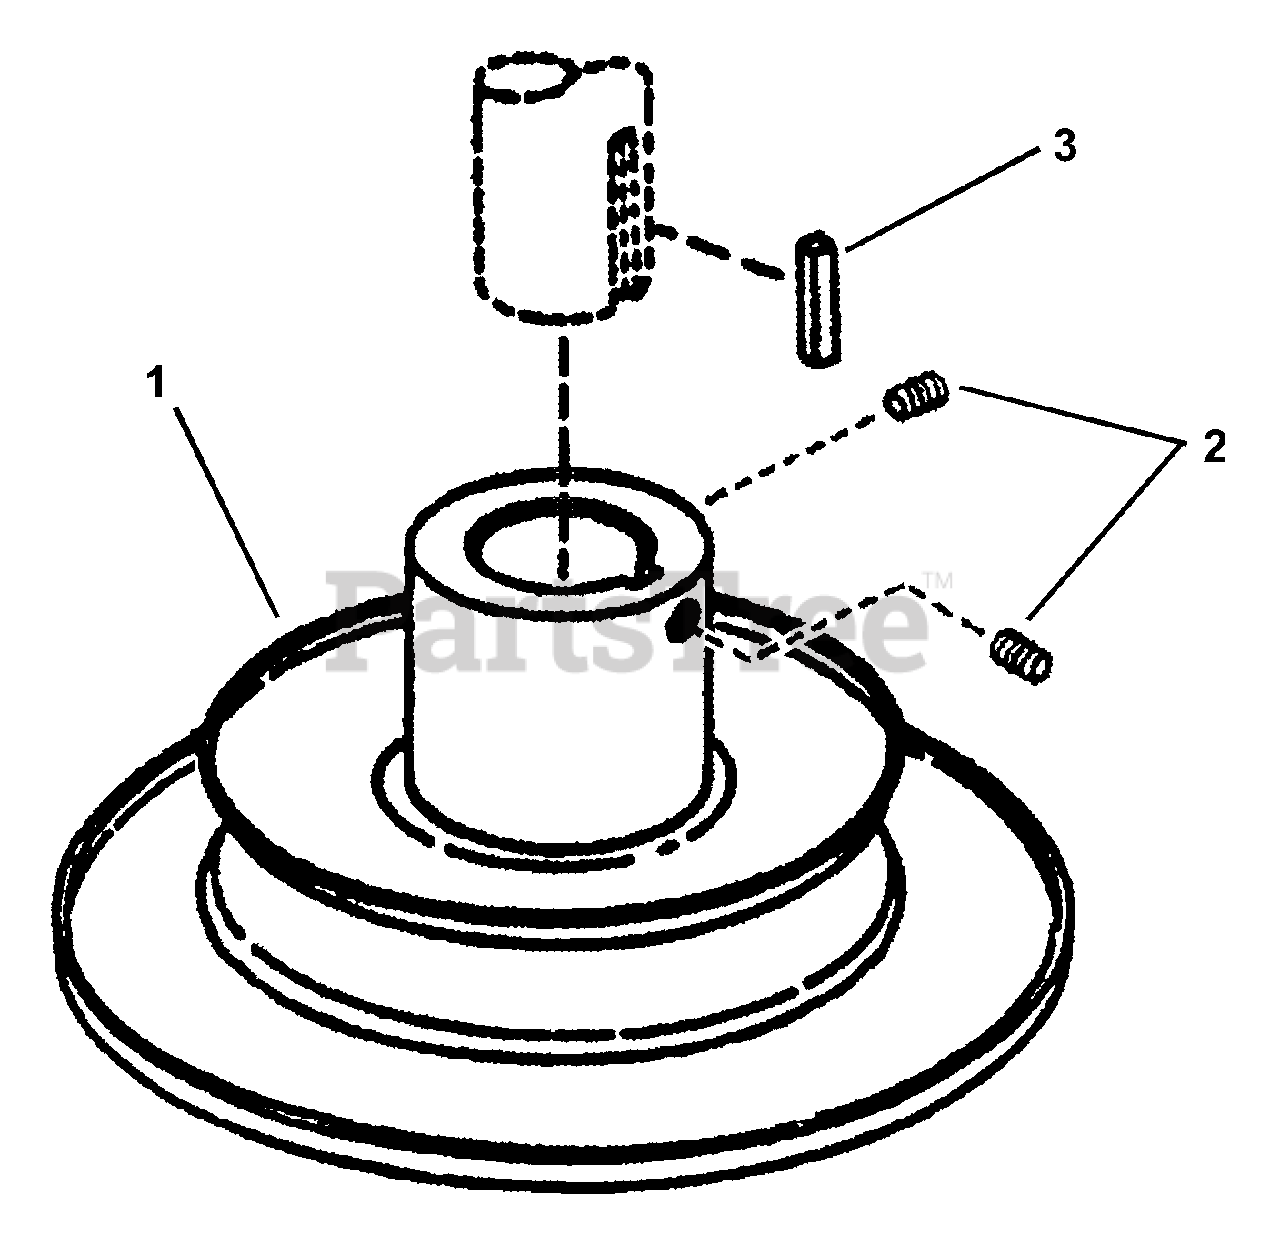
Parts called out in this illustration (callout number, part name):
1	WELDMENT, 5.75" O.D. Drive Disc
2	SCREW, 3/8-16 x 3/8" Set
3	KEY, 1/4" Square x 2"
